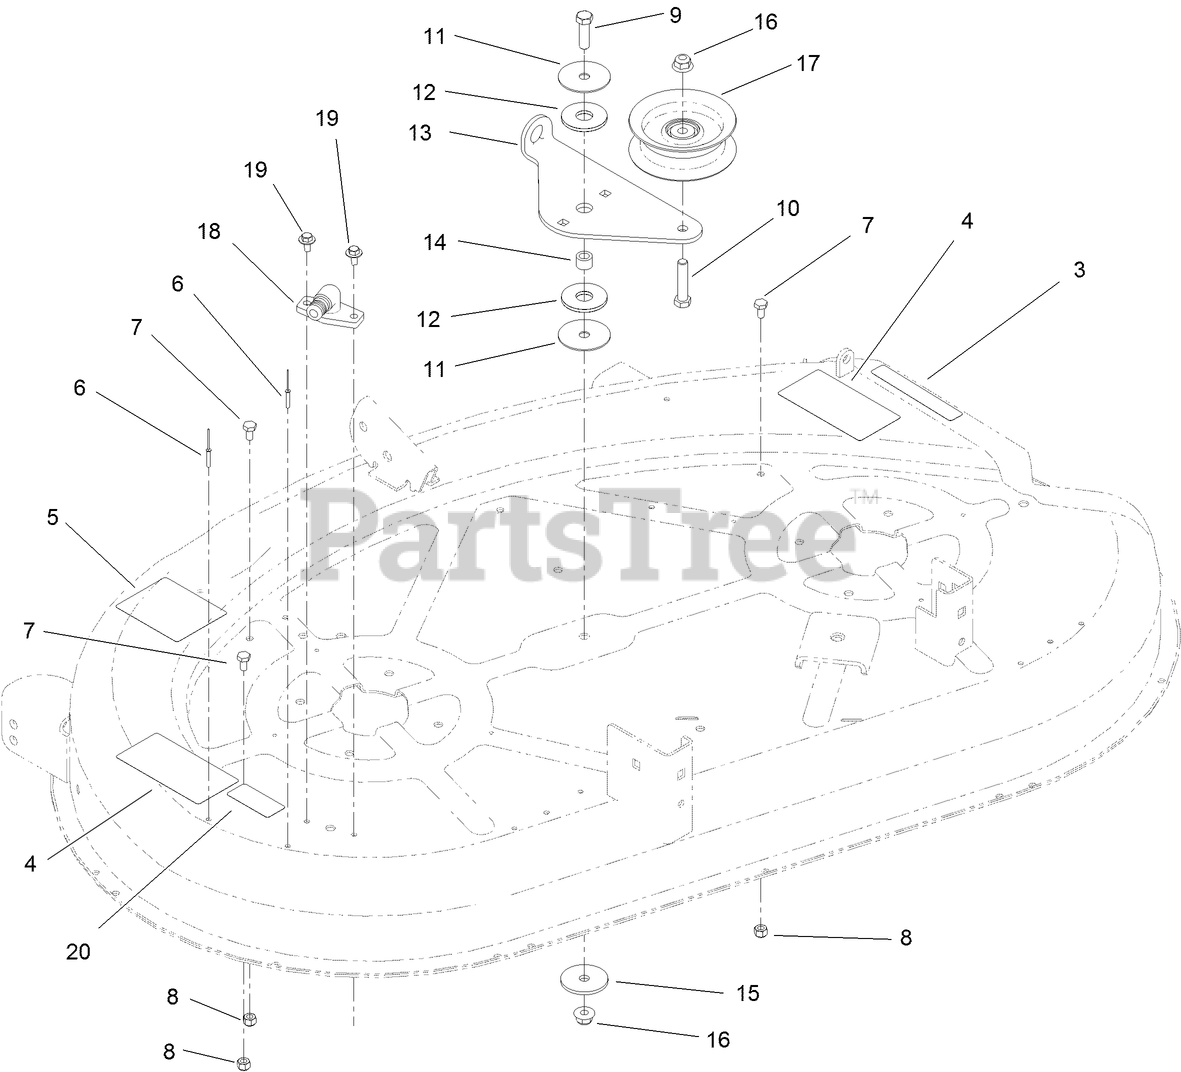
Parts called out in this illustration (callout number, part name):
3	DECAL-DANGER
4	DECAL-DANGER, DECK
5	DECAL-ROUTING, BELT
6	RIVET-BLIND
7	SCREW-HH
8	NUT-LOCK, NI
9	SCREW-HH
10	SCREW-HH
11	WASHER
12	WASHER-FRICTION, COMPOSITE
13	ARM-IDLER
14	SPACER
15	WASHER-REBOUND
16	NUT-HF, NI
17	PULLEY-IDLER, FLAT
18	FITTING-WASHOUT
19	SCREW-HHFTF
20	SERVICE DECAL
